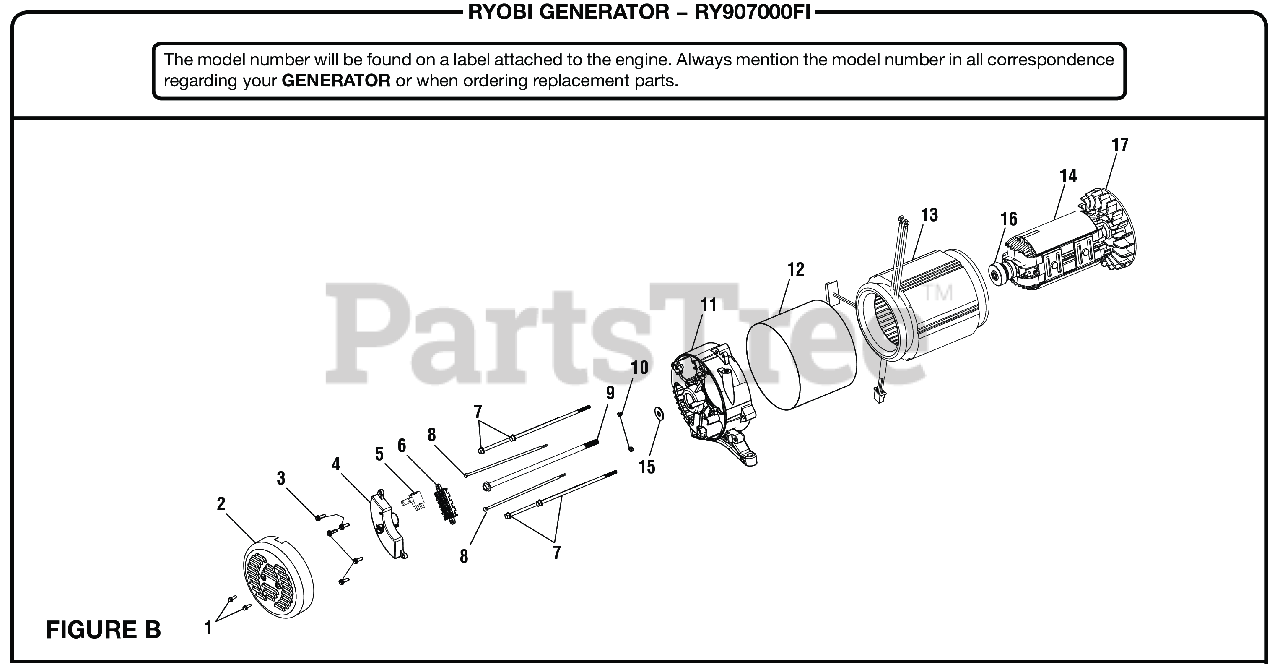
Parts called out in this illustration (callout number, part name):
1	Bolt (M5 x 12 mm, Hex Flange Hd.)
2	Brush Cover
3	Bolt (M5 x 16 mm, Hex Flange Hd.)
4	Automatic Voltage Regulator
5	Brush Assembly 190 mm
6	Terminal Block
7	Stator Bolt
8	Bolt (M6 x 229mm)
9	Bolt (M10 x 280 mm)
11	Bearing Housing
13	Stator Assembly
14	Rotor Assembly
15	Rotor Washer
16	Ball Bearing
